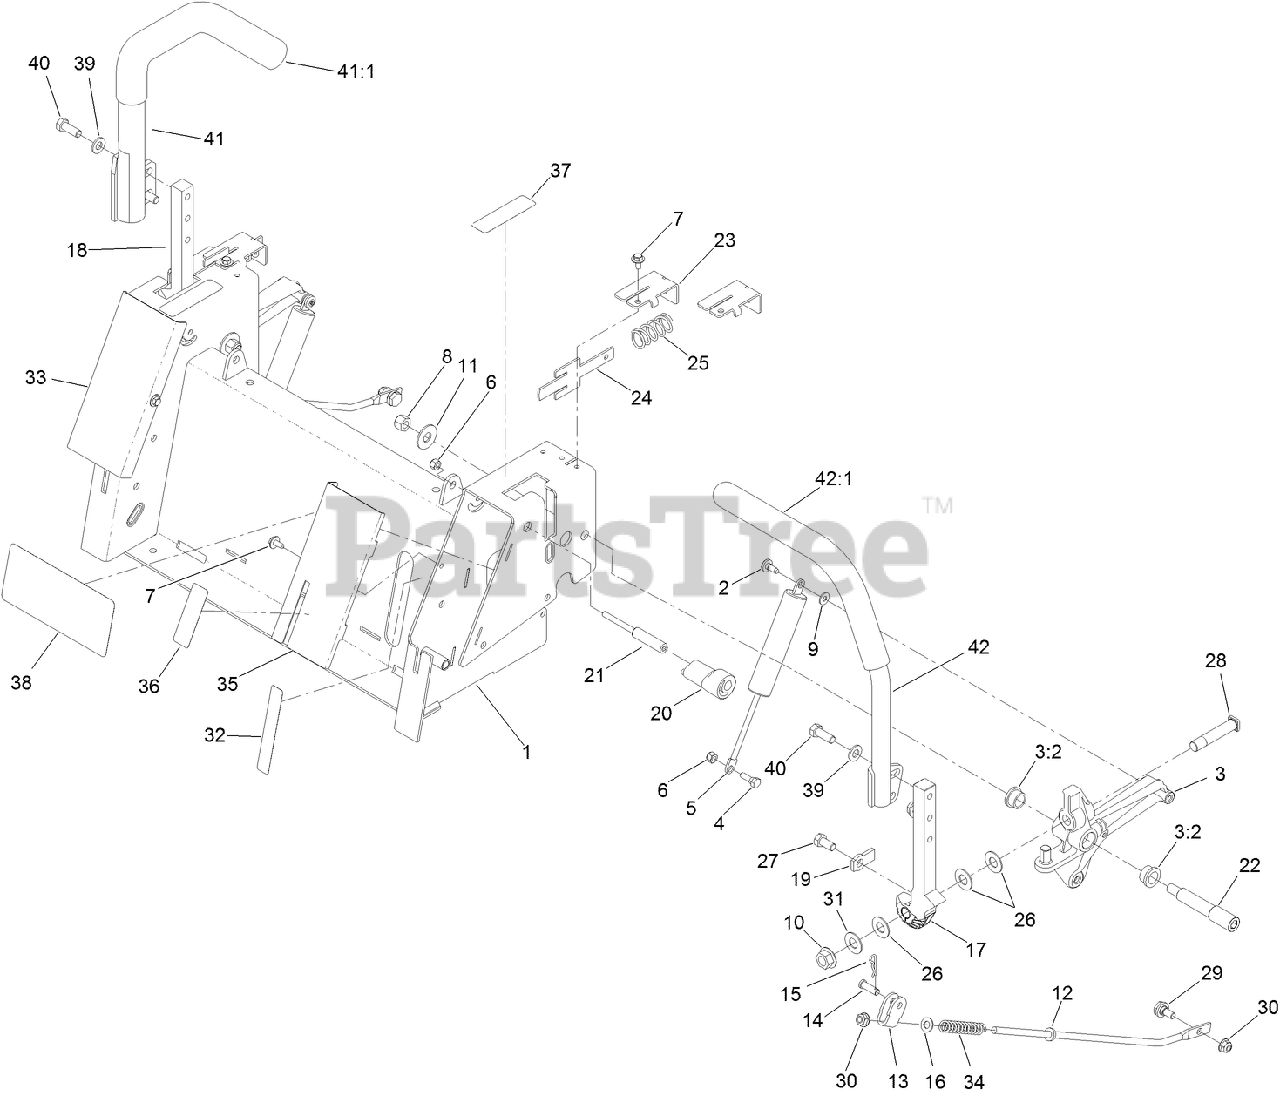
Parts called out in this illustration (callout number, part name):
1	BOX-CONTROL
2	SCREW-SHOULDER
3	ACTIVATOR ARM ASM
3:2	BUSHING
4	BOLT-SHOULDER
5	DAMPER
6	NUT-LOCK, NI
7	SCREW-HHFTF
8	NUT-LOCK, NI
9	WASHER
10	NUT-HF
11	WASHER-FLAT
12	ROD-CONTROL
13	BRACKET-CONTROL
14	PIN-CLEVIS
15	PIN-COTTER
16	WASHER-PLAIN
17	ARM-ACTUATOR, LH
18	ARM-ACTUATOR, RH
19	TAB-STOP
20	ECCENTRIC
21	SCREW-ECCENTRIC
22	BOLT-SHOULDER
23	BRACKET-RETURN
24	PLATE-RETURN
25	SPRING-COMPRESSION
26	WASHER-PIVOT
27	SCREW-HH
28	BOLT-SHOULDER
29	BOLT-SHOULDER,HFH
30	NUT-HF, NI
31	WASHER-TEFLON
32	DECAL-FILL, FUEL
33	COVER-CONTROL, RH
34	SPRING-RETURN, NEUTRAL
35	COVER-CONTROL, LH
36	DECAL-BRAKE, PARKING
37	DECAL-CONTROL, MOTION
39	WASHER-FLAT
40	SCREW-HH
41	RH LEVER/GRIP ASM
41:1	GRIP-CONTROL, MOTION
42	LH LEVER/GRIP ASM
42:1	GRIP-CONTROL, MOTION
